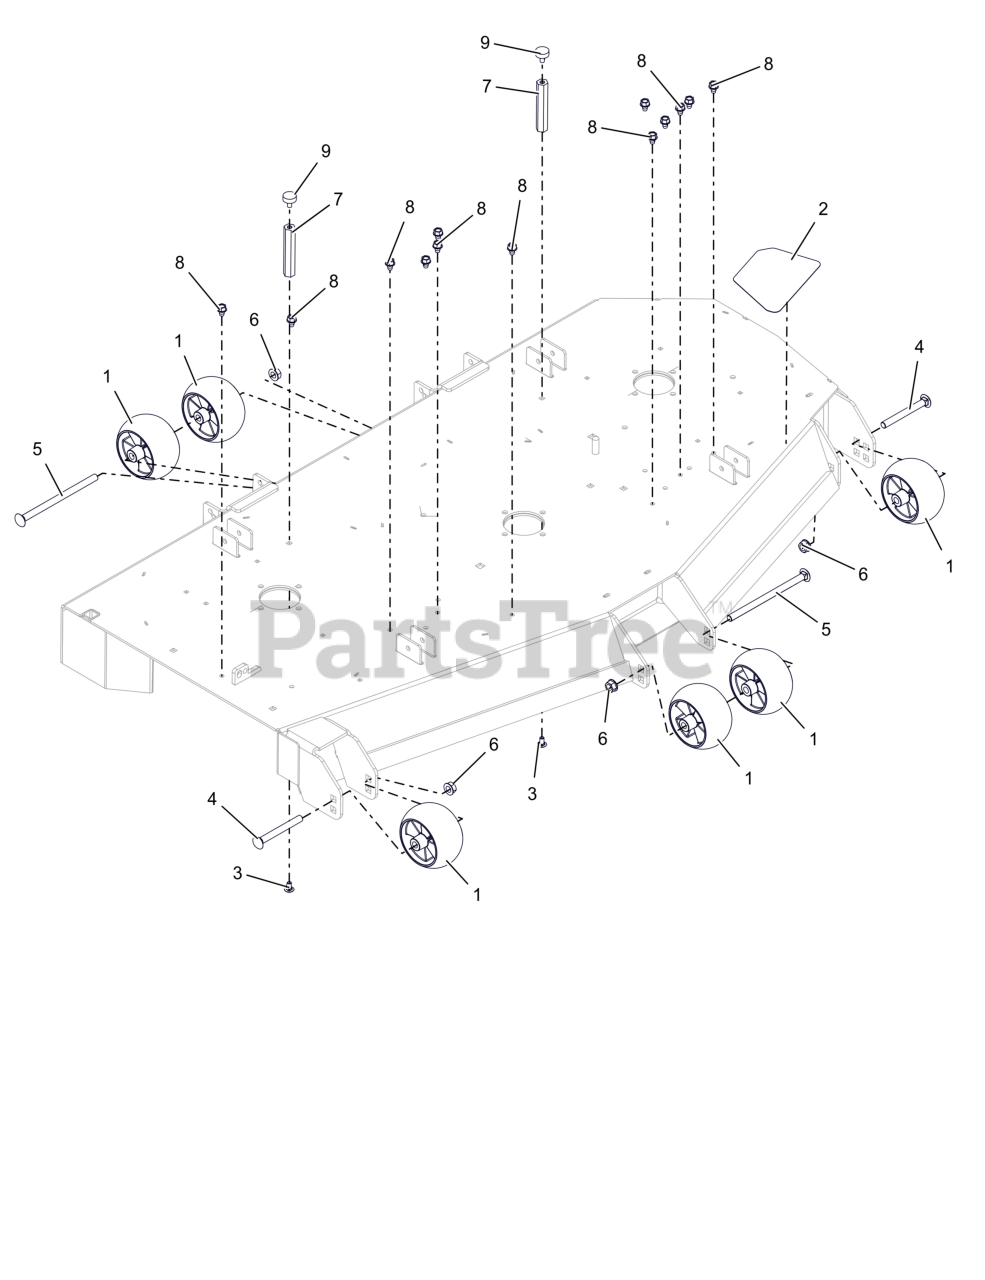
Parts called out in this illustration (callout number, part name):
1	WHEEL, ANTI SCALP - 5X3 CTR W/RIBS
2	GRIP, STEP ANTI SKID
3	BTL,RHSSN .313-18 X 0.625 G5 ZCC
4	BLT,RHNS .50-13X4.50 G5 ZCC NS
5	BLT,RHSN .50-13X8.00 G5 ZCC NS
6	NUT-LK-CTR-FLG .500-13 GG ZCC
7	NUT, COUPLING .312-18 X 4.295
8	SCR,TAP .375-16X.50 HWH TR ZCC
9	BUMPER, RUBBER
